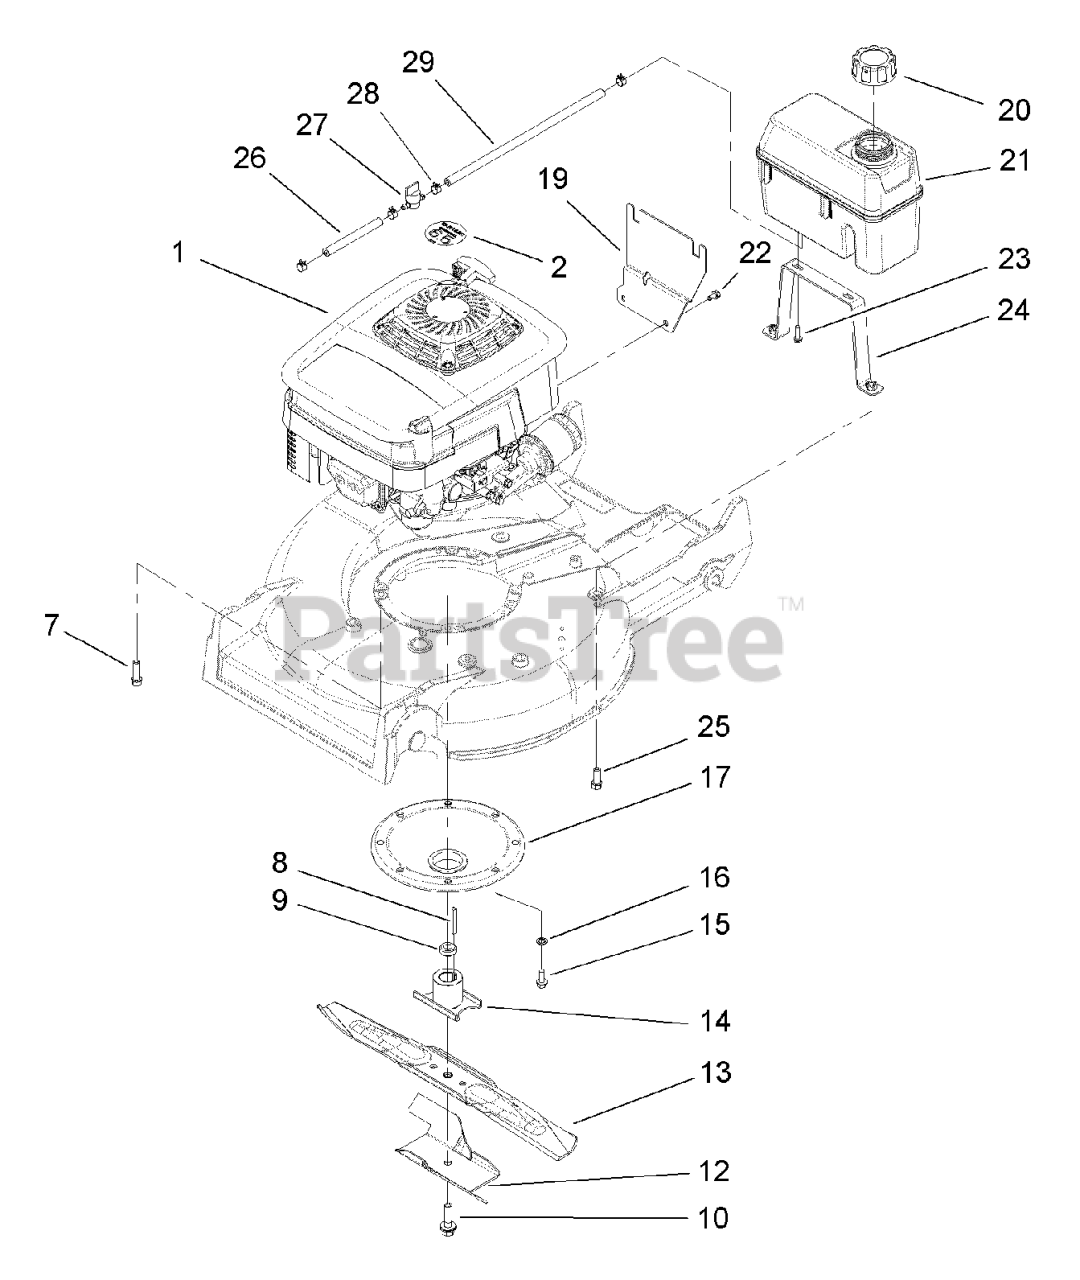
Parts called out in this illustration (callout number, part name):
2	Decal-Recoil
7	SCREW-TAPTITE
8	KEY-SQUARE
9	SPACER-RETAINER, BLADE
12	STIFFENER-BLADE
15	Screw-HWH 5/16-18 X 3/4 Tf
16	WASHER-LOCK, INTERNAL
17	PROTECTOR-CRANKSHAFT
19	BRACKET-TANK
20	CAP-GAS
22	SCREW-HWH
23	SCREW-HWH
25	SCREW-TAPTITE
27	VALVE-FUEL
28	CLAMP-HOSE
